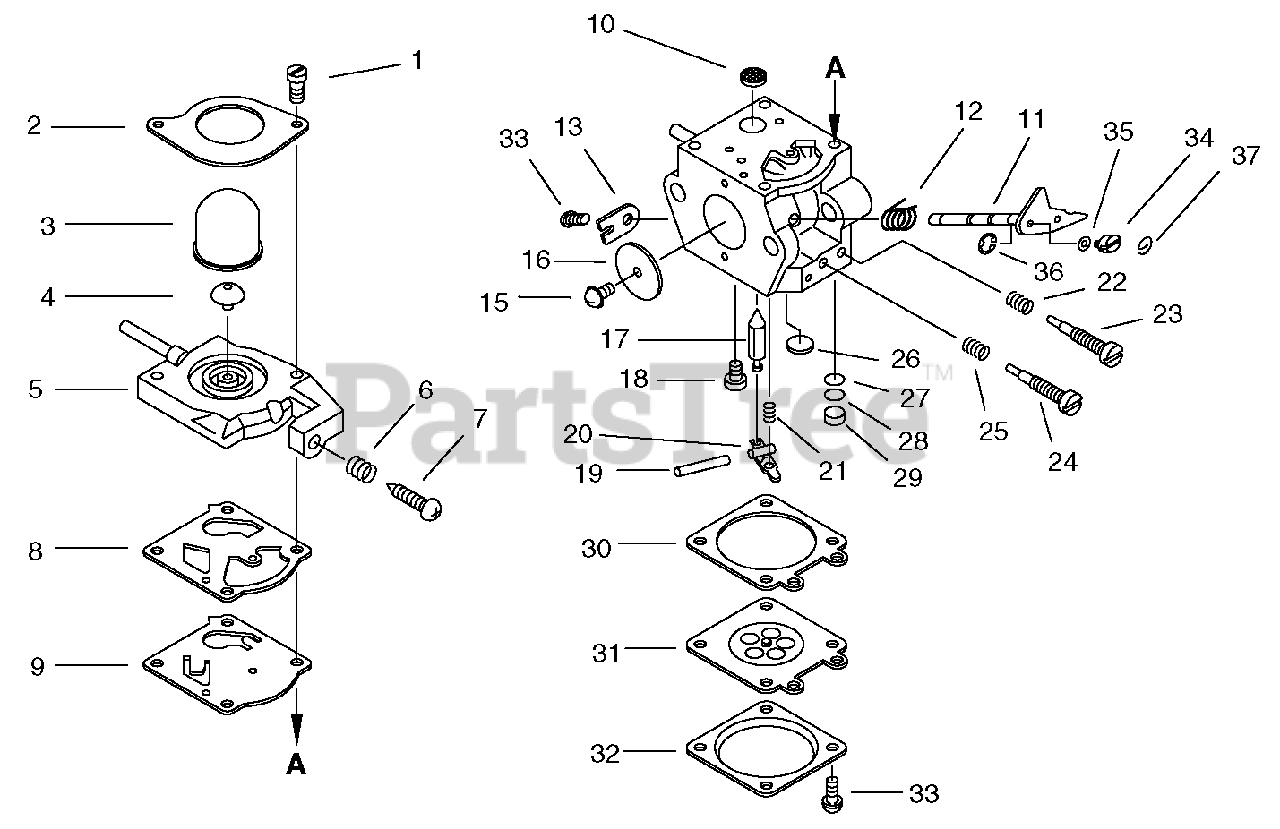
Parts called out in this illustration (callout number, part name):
1	SCREW, PUMP COVER
2	RETAINER, PURGE BULB
3	BULB, PURGE
4	VALVE, CHECK
5	COVER, PUMP
6	SPRING, IDLE ADJUST
7	SCREW, IDLE ADJUST
8	GASKET, PUMP
9	DIAPHRAGM, PUMP
10	STRAINER
11	SHAFT, THROTTLE
12	SPRING, THROTTLE RETURN
13	CLIP, THROTTLE SHAFT
16	VALVE, THROTTLE
17	VALVE, INLET NEEDLE
18	SCREW, METERING LEVER PIN
19	PIN, METERING LEVER
20	LEVER, METERING
21	SPRING, METERING LEVER
23	NEEDLE - HIGH SPEED
24	NEEDLE - LOW SPEED
26	PLUG, WELCH
27	SCREEN, SPARK ARRESTOR
28	RING, RETAINING
29	PLUG, WELCH
30	GASKET, METERING
31	DIAPHRAGM, METERING
32	COVER, METERING
36	RING, RETAINING
